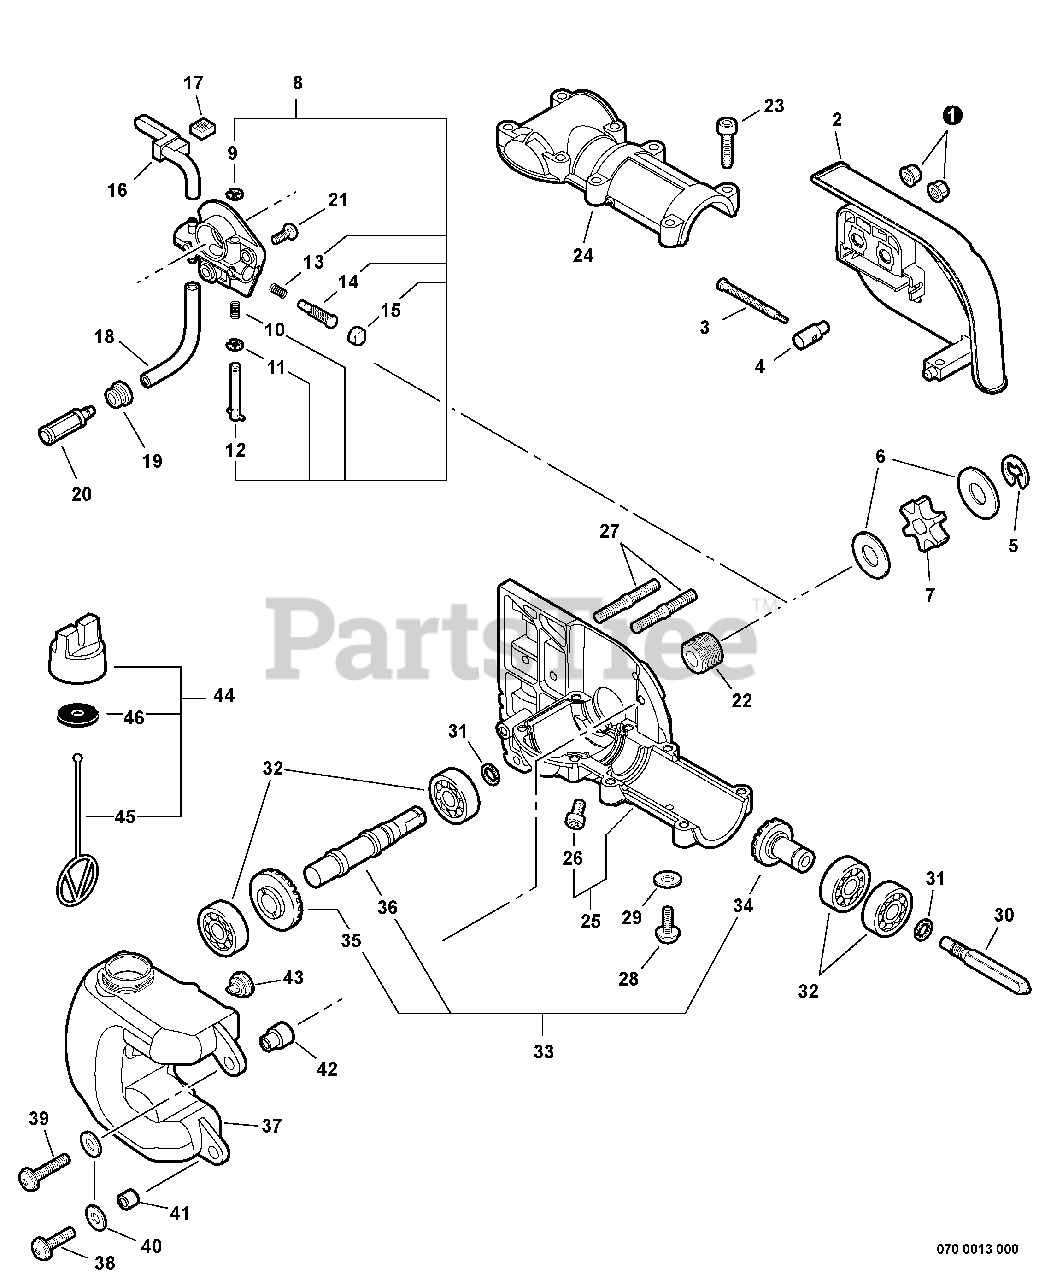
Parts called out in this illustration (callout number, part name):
1	NUT - 6 -- FLANGE
2	GUARD, SPROCKET
3	SCREW, TENSIONER
4	TENSIONER, CHAIN
5	RING, RETAINING
7	SPROCKET, DRIVE
8	AUTO-OILER ASSY
9	RING, RETAINING
12	NEEDLE, ADJUST
13	SPRING, PLUNGER
14	PLUNGER ASSY
15	CAP, OIL PUMP
16	PIPE, OIL OUTLET
17	PAD, FOAM
18	PIPE - 3X6X75 -- BLACK
19	GROMMET
20	FILTER, OIL
21	SCREW - 5X10
22	GEAR - WORM
23	SCREW - 5X25
24	CASE, GEAR - UPPER
25	GEAR CASE ASSY - LOWER
26	SCREW - 5X10
27	STUD - 6
28	SCREW - 5X10
29	WASHER - 5
30	CONNECTOR, SHAFT
31	RING, RETAINING - 12
32	BEARING, BALL - 6001
33	GEAR SET
34	GEAR - BEVEL
35	GEAR - BEVEL
36	GEAR - SHAFT
37	TANK, OIL
38	SCREW - 5X16
39	SCREW - 5X25
40	WASHER - 5
44	CAP ASSY
45	CONNECTOR, CAP
46	GASKET, CAP
